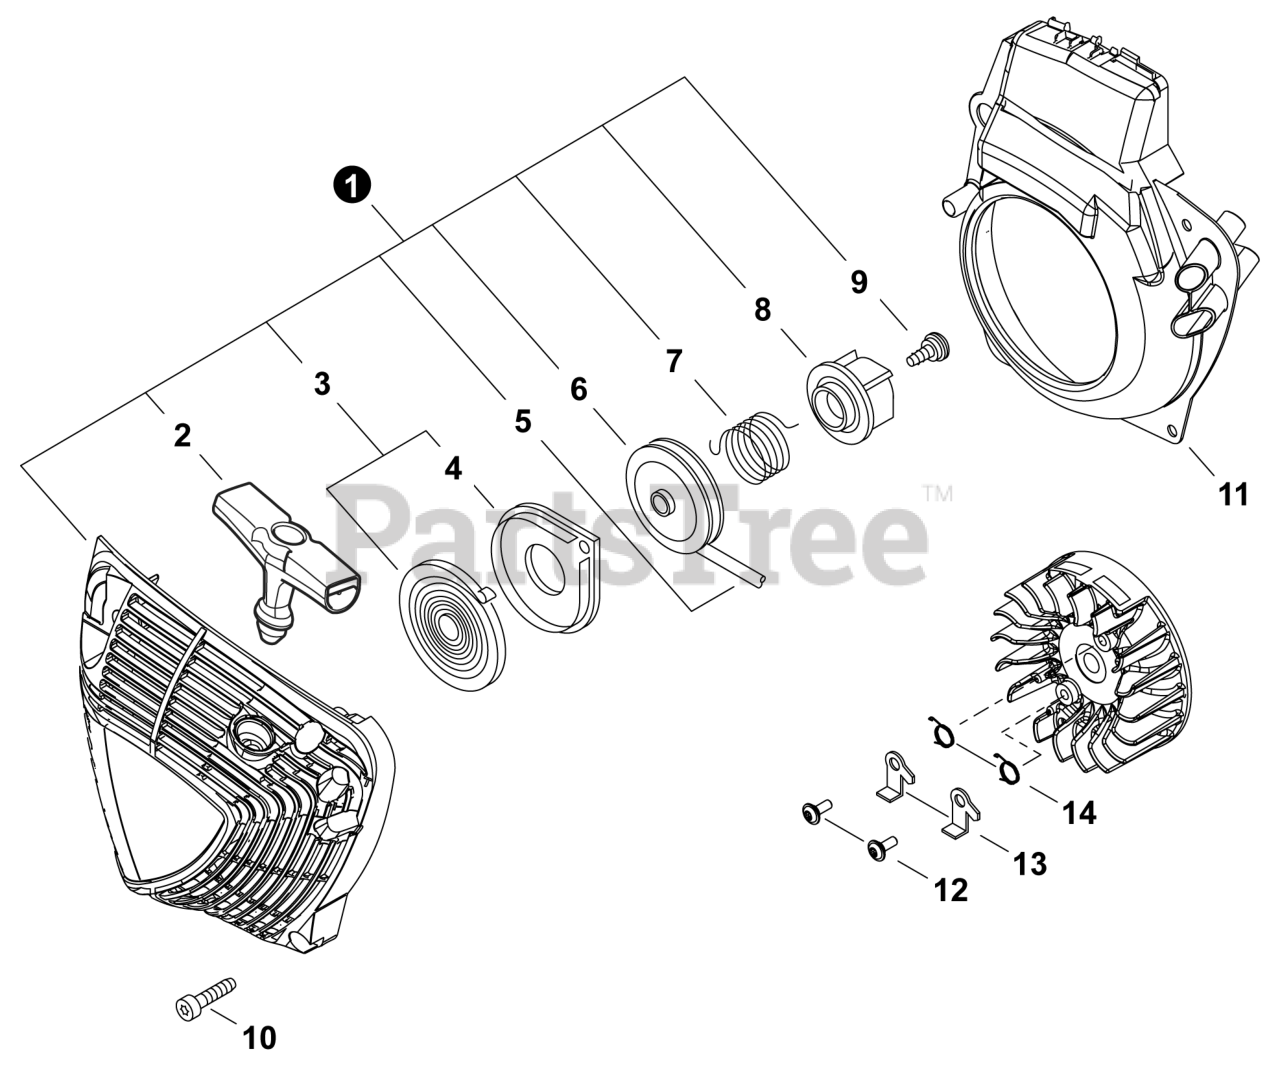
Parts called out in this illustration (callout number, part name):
1	STARTER, RECOIL
2	GRIP, STARTER
3	SPRING KIT, RECOIL
4	SPRING CASE
5	ROPE, STARTER
6	REEL, ROPE
7	SPRING, TORSION
8	PAWL CATCHER
9	SCREW 5
10	BOLT, TORX 5x20
11	COVER, FAN
12	BOLT 5x11
14	SPRING, TORSION
